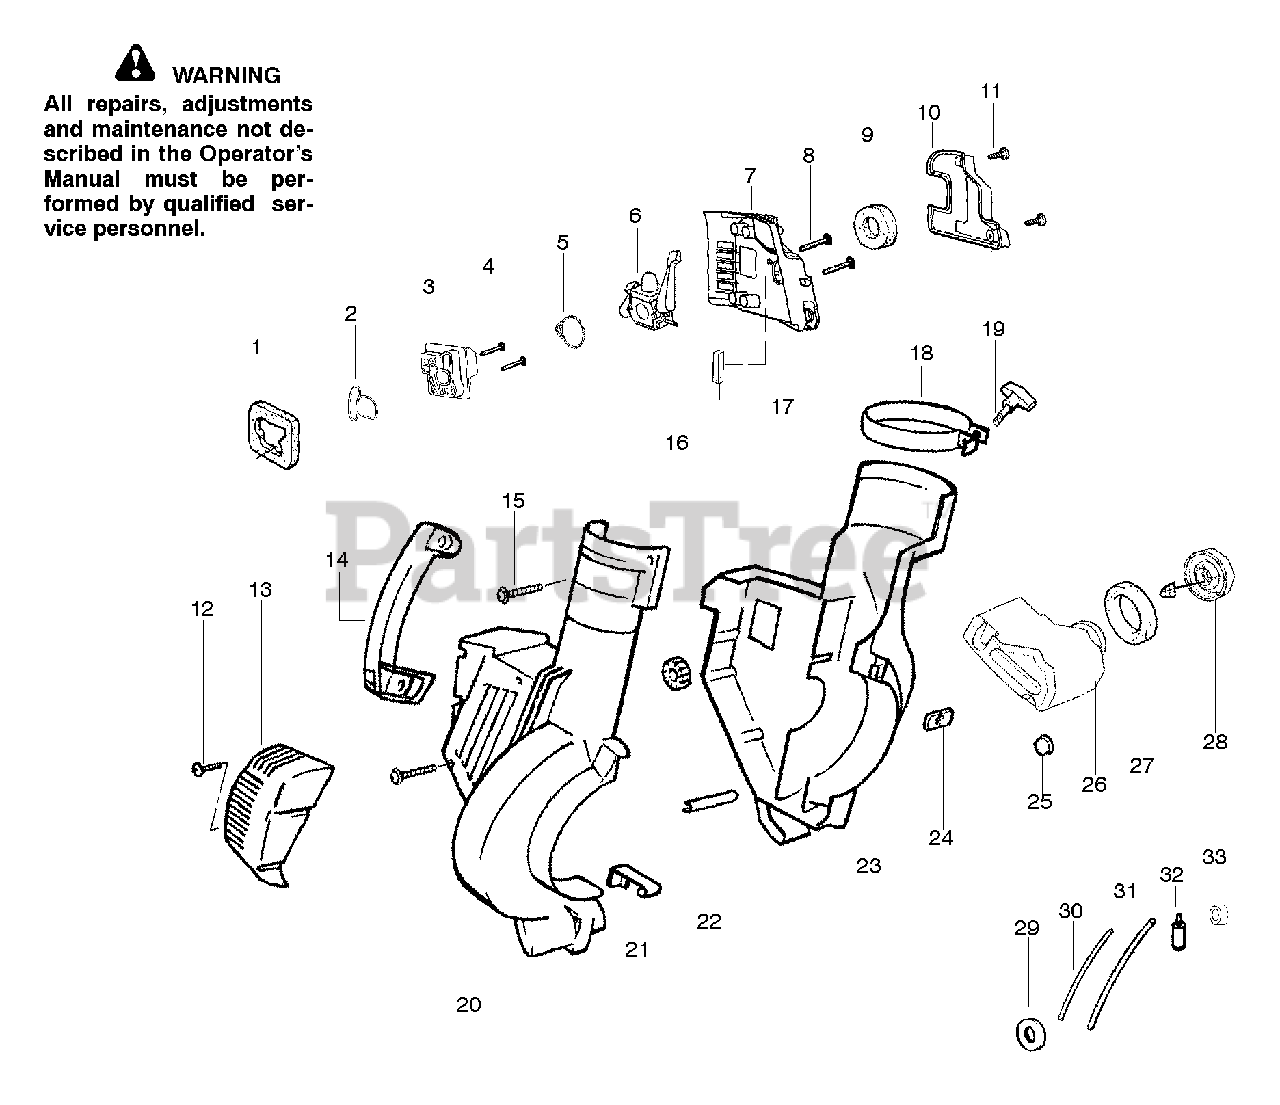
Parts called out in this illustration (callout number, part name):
1	Air Dam (kit)
2	Gasket-Carb. Adapter/Cycl.
3	Carburetor Adaptor
5	Gasket-Carburetor
6	Kit-Carb Ass'y (C1Q-W11)
7	Air Box-Purple
8	Screw-Carb.
9	Filter-Air
10	Cover-Purple Air Filter
11	Screw-Air Box Cover
13	Assy-Purple Muffler Cover
16	Isolator
17	Foam 25.4mm (kit)
18	Clamp-Blower Tube
19	Knob-Tube Clamp
20	Shroud-Green Right
21	Spring-Cover Latch
22	Guide-Starter Rope
23	Shroud-Green Left
25	Isolator-Crankcase
26	Assy-Fuel Tank
27	Gasket-Fuel Tank
28	Fuel Cap w/Retainer
29	Grommet-Shroud
30	Kit-Line Carb/Purge
31	Kit-Line Tank/Purge
32	Assy-Fuel Pick-up
33	Grommet-Fuel line (kit)
